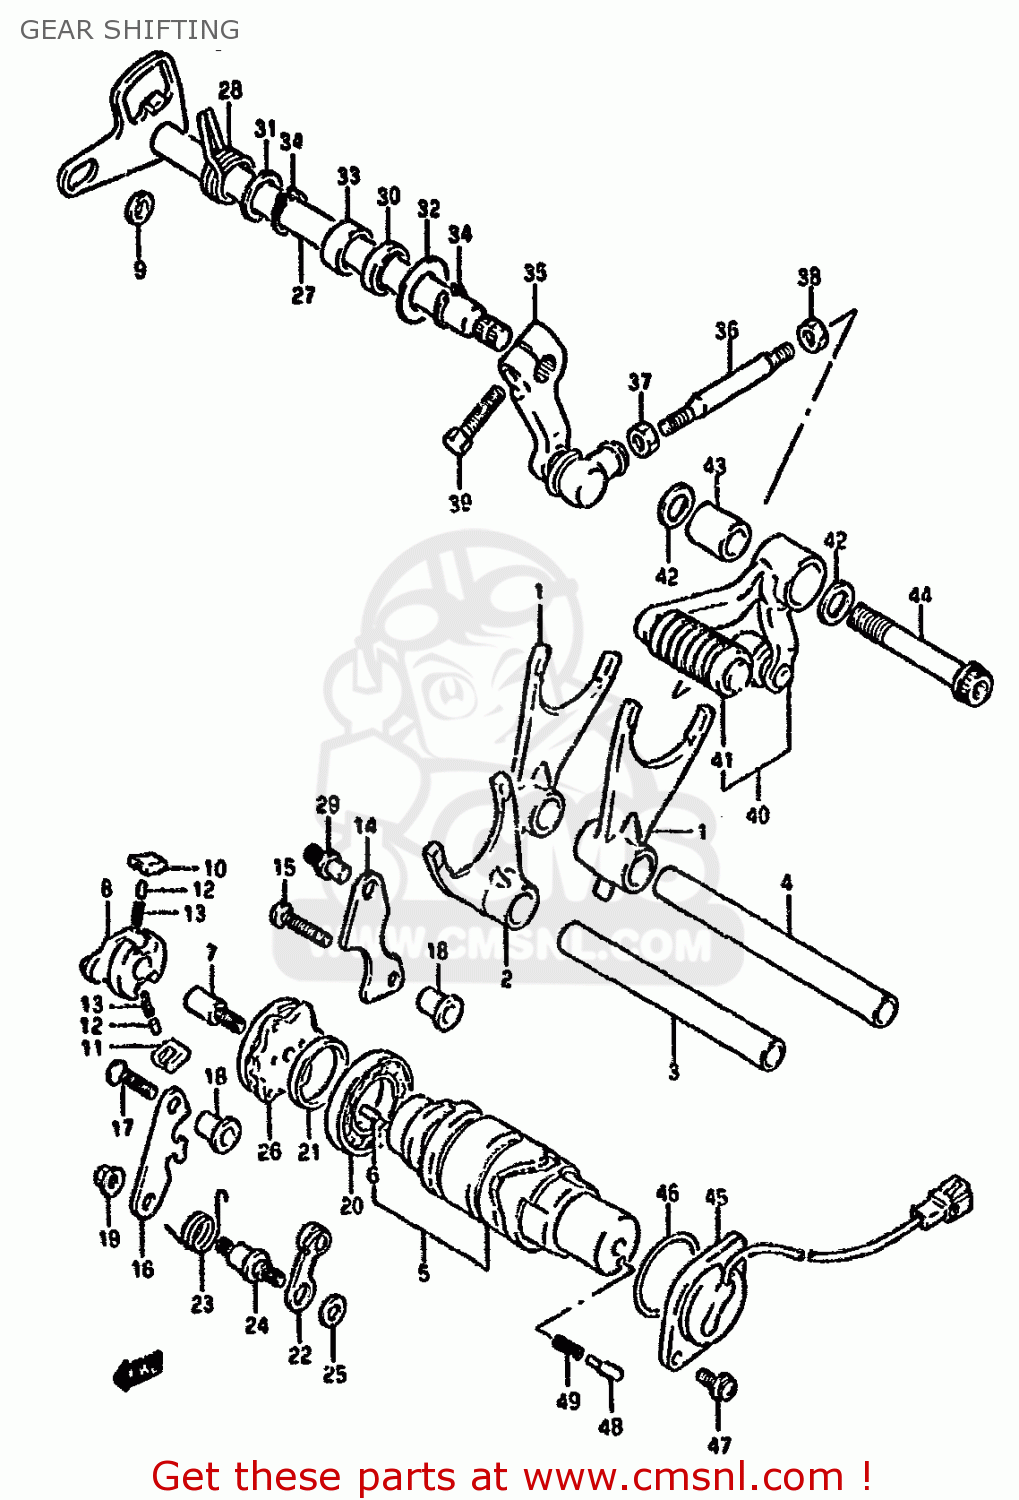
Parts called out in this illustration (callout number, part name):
1	FORK,GEAR SHIFT NO.1
2	FORK,GEAR SHIFT NO.3
3	SHAFT,GEAR SHIFT FORK
4	SHAFT,GEAR SHIFT FORK(L:128)
5	CAM COMP,GEAR SHIFT
6	PIN
7	PIN,SHIFT CAM DRIVEN GEAR
8	SHIFTER,GEAR SHIFT CAM
9	SPACER(7X10X5)
10	PAWL,GEAR SHIFT NO.1
11	PAWL,GEAR SHIFT NO.2
12	PIN(5X8)
13	SPRING
14	LIFTER,GEAR SHIFT PAWL
15	SCREW 6X30
16	GUIDE,GEAR SHIFT CAM
17	SCREW
18	SPACER(6.1X10X16)
19	NUT
20	BEARING(25X47X8)
21	WASHER(25X32X3)
22	STOPPER,GEAR SHIFT CAM
23	SPRING,STOPPER ARM
24	SUPPORT,CAM STOPPER ARM
25	WASHER
26	PLATE,GEAR SHIFT CAM
27	SHAFT COMP,GEAR SHIFTING
28	SPRING
29	STOPPER,GEAR SHIFT CAM
30	SEAL,OIL(14X22X6)
31	WASHER,THRUST
32	WASHER
33	BEARING(14X20X12)
34	CIRCLIP
35	ARM,GEAR SHIFT LINK
36	ROD,GEAR SHIFT LINK
37	NUT
38	NUT
39	BOLT
40	LEVER ASSEMBLY,GEAR SHIFTING
41	RUBBER,GEAR SHIFT PEDAL
42	WASHER
43	SPACER(10X18X22)
44	BOLT
45	TERMINAL BASE ASSY,NEUTRAL
46	O RING(D:2.4,ID:36.5)
47	SCREW
48	PIN(5X15.5)
49	SPRING
